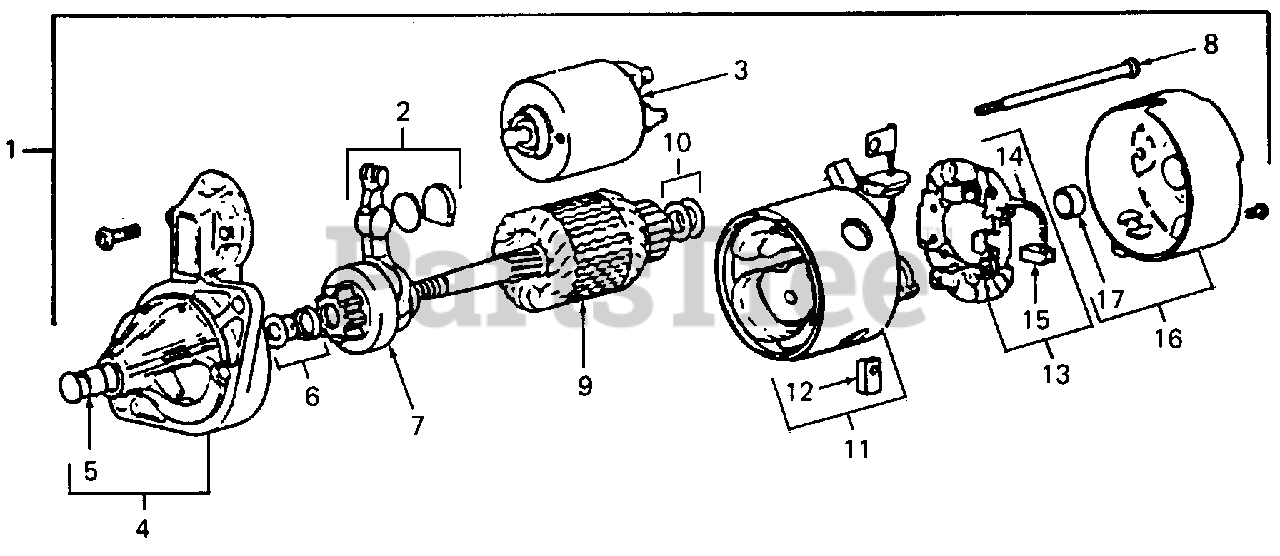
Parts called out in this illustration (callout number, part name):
1	Starter Assy
3	Switch, Magnetic
4	Frame, Drive End
7	Clutch, Over Running
10	Washer, Adjusting
13	Holder, Brush
14	Spring, Brush
